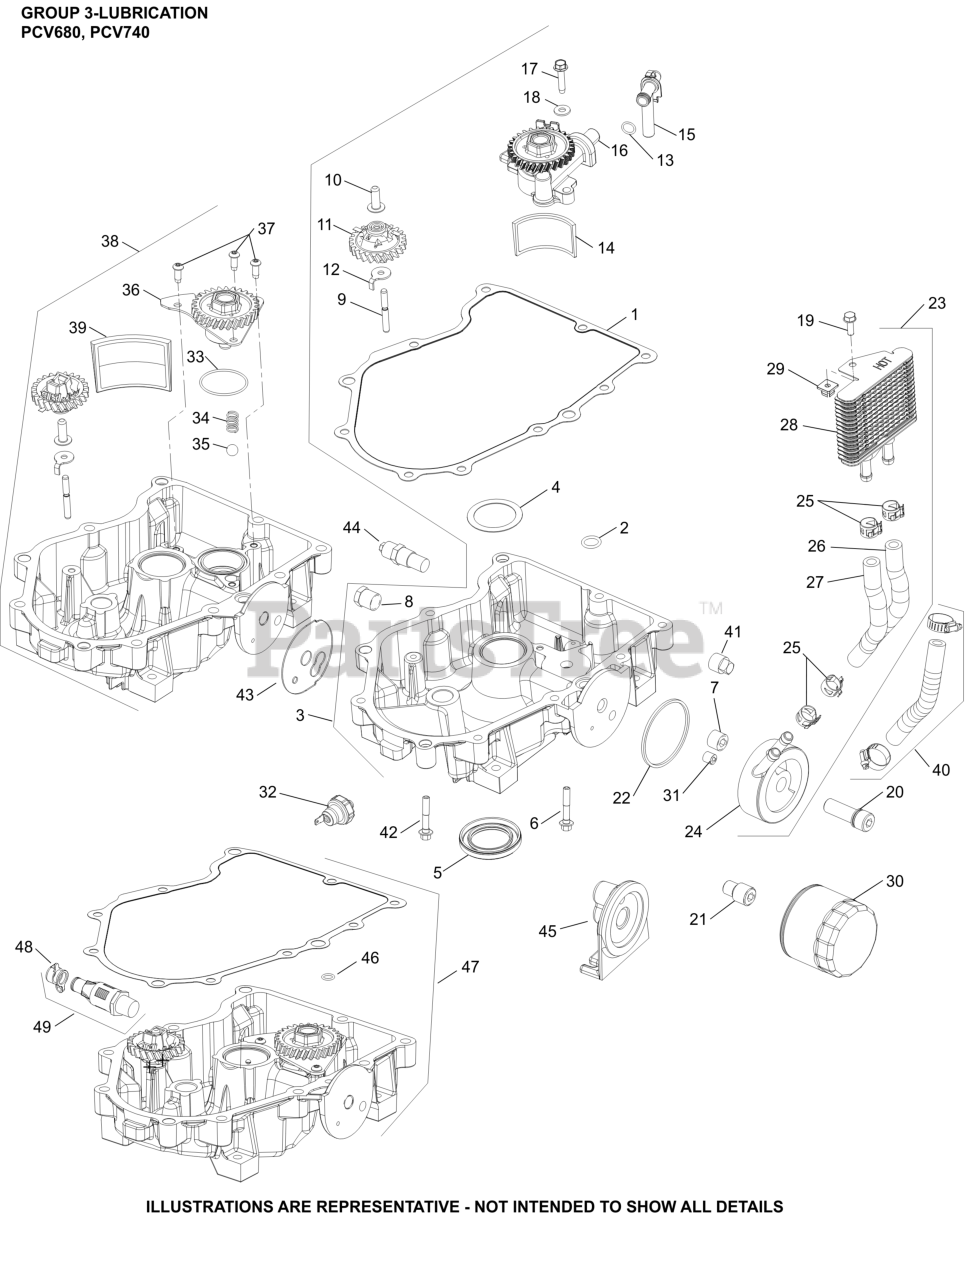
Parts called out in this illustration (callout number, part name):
1	GASKET, OIL PAN
6	SCREW, FLG M8X1.25X45
7	PLUG, PIPE CTSK 3/8"
9	SHAFT, GOVERNOR GEAR
10	PIN, GOVERNOR REGULATING
11	KIT, GOVERNOR GEAR W/PIN
12	TAB, LOCKING
19	SCREW, TAP M6X1.7X18
20	NIPPLE, OIL FILTER - (#2413608S)
22	O-RING, OIL COOLER
23	COOLER, OIL & DIVERTER ASSEMBLY
24	ADAPTER, OIL FILTER (CV EFI)
25	CLAMP, HOSE LOW PROFILE
29	NUT, PLASTIC - BLACK
30	OIL FILTER
32	SENSOR, OIL PSI
33	O-RING (1.78" DIA)
34	SPRING, COMPRESSION
35	PRESSURE RELIEF BALL
36	PUMP, OIL ASSEMBLY
37	SCREW, BUTTON HEAD
39	SCREEN, OIL
40	KIT, HOSE 140MM
42	SCREW, HEX FLANGE
46	O-RING (.5" DIA)
47	PAN, ASSEMBLY OIL (SERVICE)
